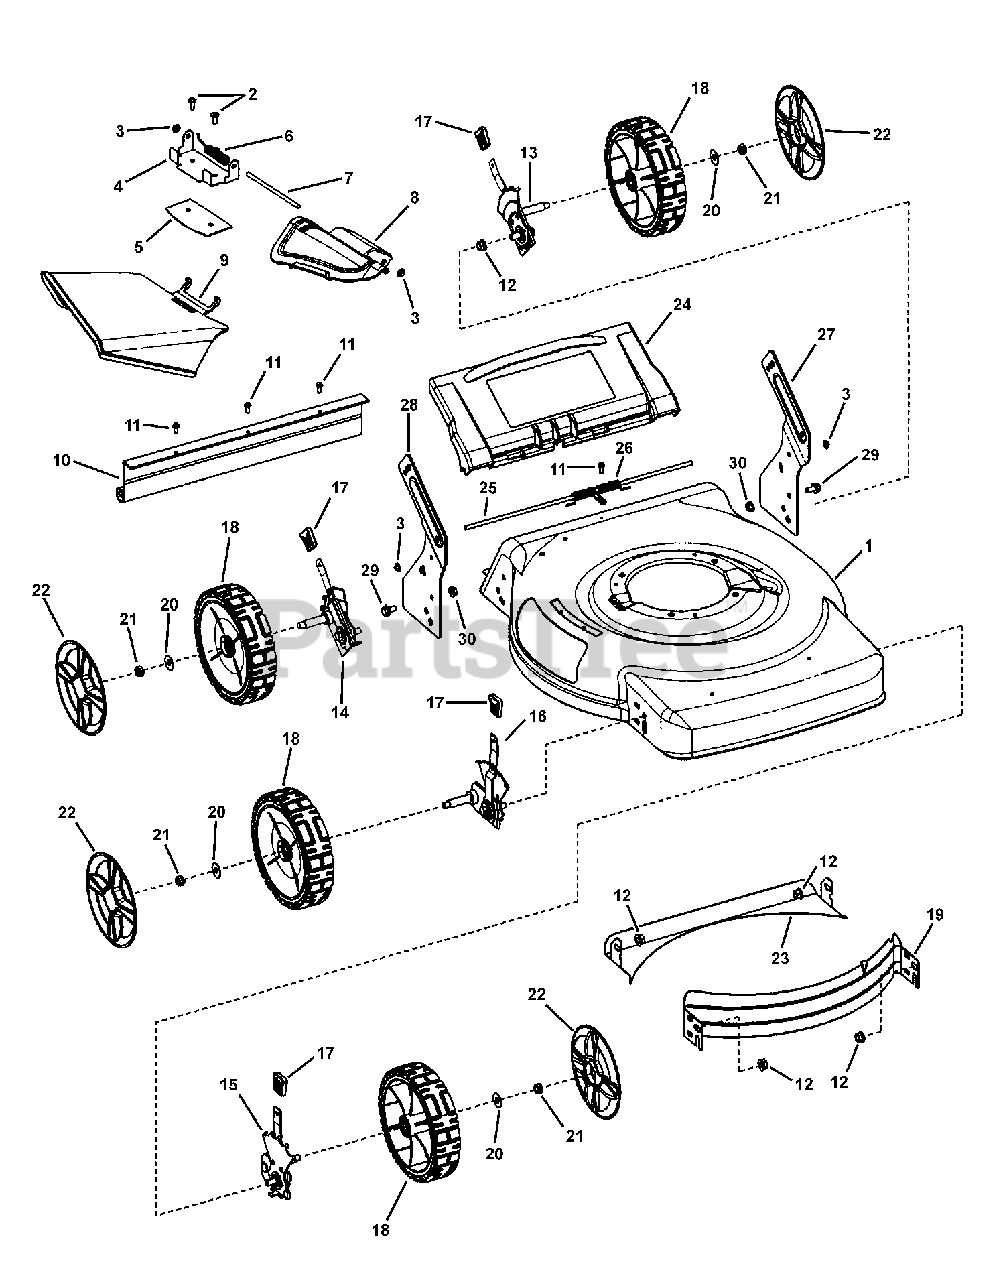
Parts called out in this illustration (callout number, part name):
1	DECK, 22" Walk
2	SCREW, 1/4-20 x 11/16" Pan Head Self-Tap (Torx)
3	PUSHNUT, 1/4"
4	BRACKET, Chute
5	PLATE, Mulch, 22" RB Scott's
6	SPRING, Chute (Torsion)
7	ROD, Pivot (1/4" Dia. x 5.55")
8	COVER, Mulch, Plastic, Black
9	SIDE CHUTE, Plastic, Black
10	GUARD, Rear
11	SCREW, #10-24 x 1/2" Hex Washer Self-Tap (Sems)
12	NUT, 3/8-16 Hex Flange Lock, YZ
13	ASSY, Height-Of-Cut, Left Rear, 22" WBM
14	ASSY, Height-Of-Cut, Right Rear, 22" WBM
15	ASSY, Height-Of-Cut, Left Front, 22" WBM, Push
16	ASSY, Height-Of-Cut, Right Front, 22" WBM, Push
17	GRIP, Height Latch - Black (1.3" Wide)
18	ASSY, Wheel & Bearing, 8 x 2 Idle, DW Tread
19	BAFFLE, Front, 22" WBM
20	WASHER, 1" O.D. x .387 I.D. Flat
21	NUT, 3/8-16 Hex Center Lock, YZ
22	HUBCAP, Black
23	BAFFLE, Rear, 22" Deck
24	DOOR, 22" Rear
25	ROD, Pivot, Rear Door (1/4" Dia. X 17-1/2")
26	SPRING, Torsion, Rear Door, 22" WBM
27	BRACKET, Lower Handle, LH, 22" WBM
28	BRACKET, Lower Handle, RH, 22" WBM
29	SCREW, 5/16-18 x 3/4" Hex Head Cap, GR 5
30	NUT, 5/16-18 Flange Lock, YZ
